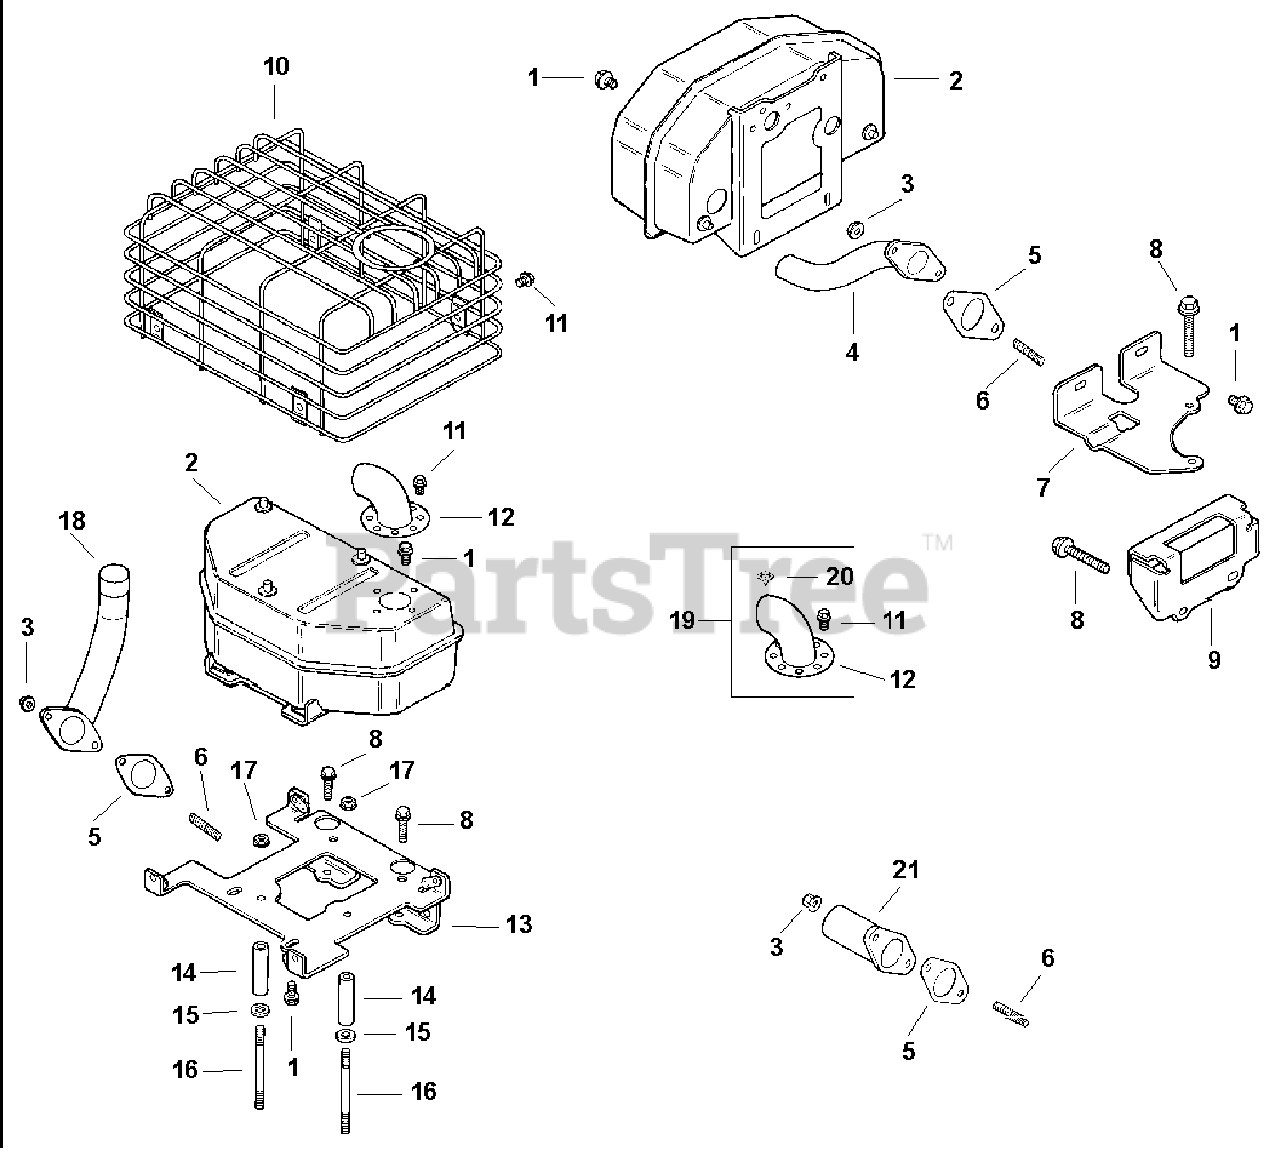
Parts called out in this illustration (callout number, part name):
1	Screw, hex. flange M6x1.0x16
3	NUT - USE M-841080
4	PIPE, INLET
5	GASKET, EXHAUST MANIFOLD
6	STUD - USE M-829033
7	BRACKET, MUFFLER
8	SCREW - USE M-645025
9	BRACKET, MUFFLER
10	GUARD, MUFFLER
11	Screw, hex. flange M5x0.8x10
12	DEFLECTOR, EXHAUST
